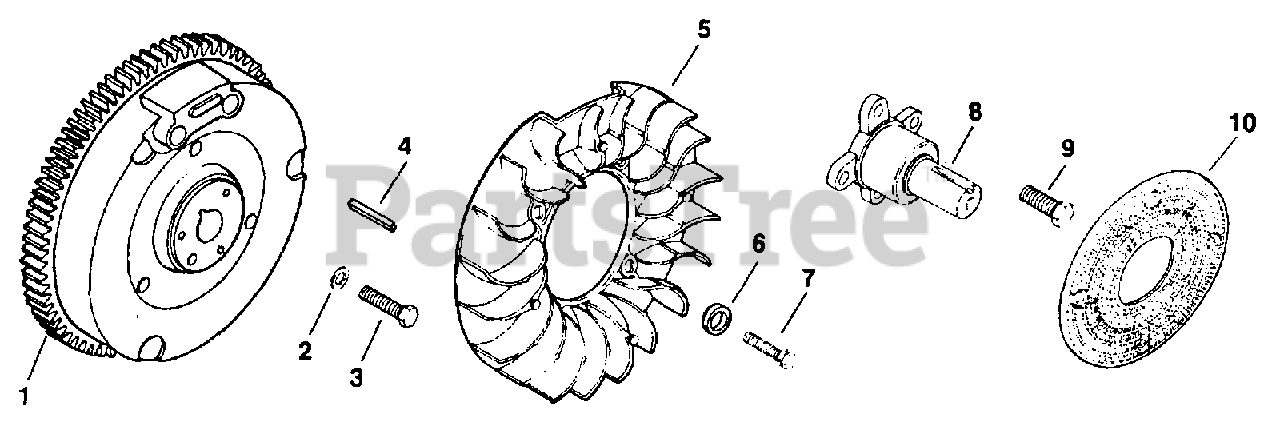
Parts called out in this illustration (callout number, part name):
1	FLYWHEEL
2	WASHER
3	SCREW
4	KEY
5	FAN
6	SPACER
7	SCREW
8	SHAFT, FRONT DRIVE
9	SCREW
10	SCREEN, GLASS
